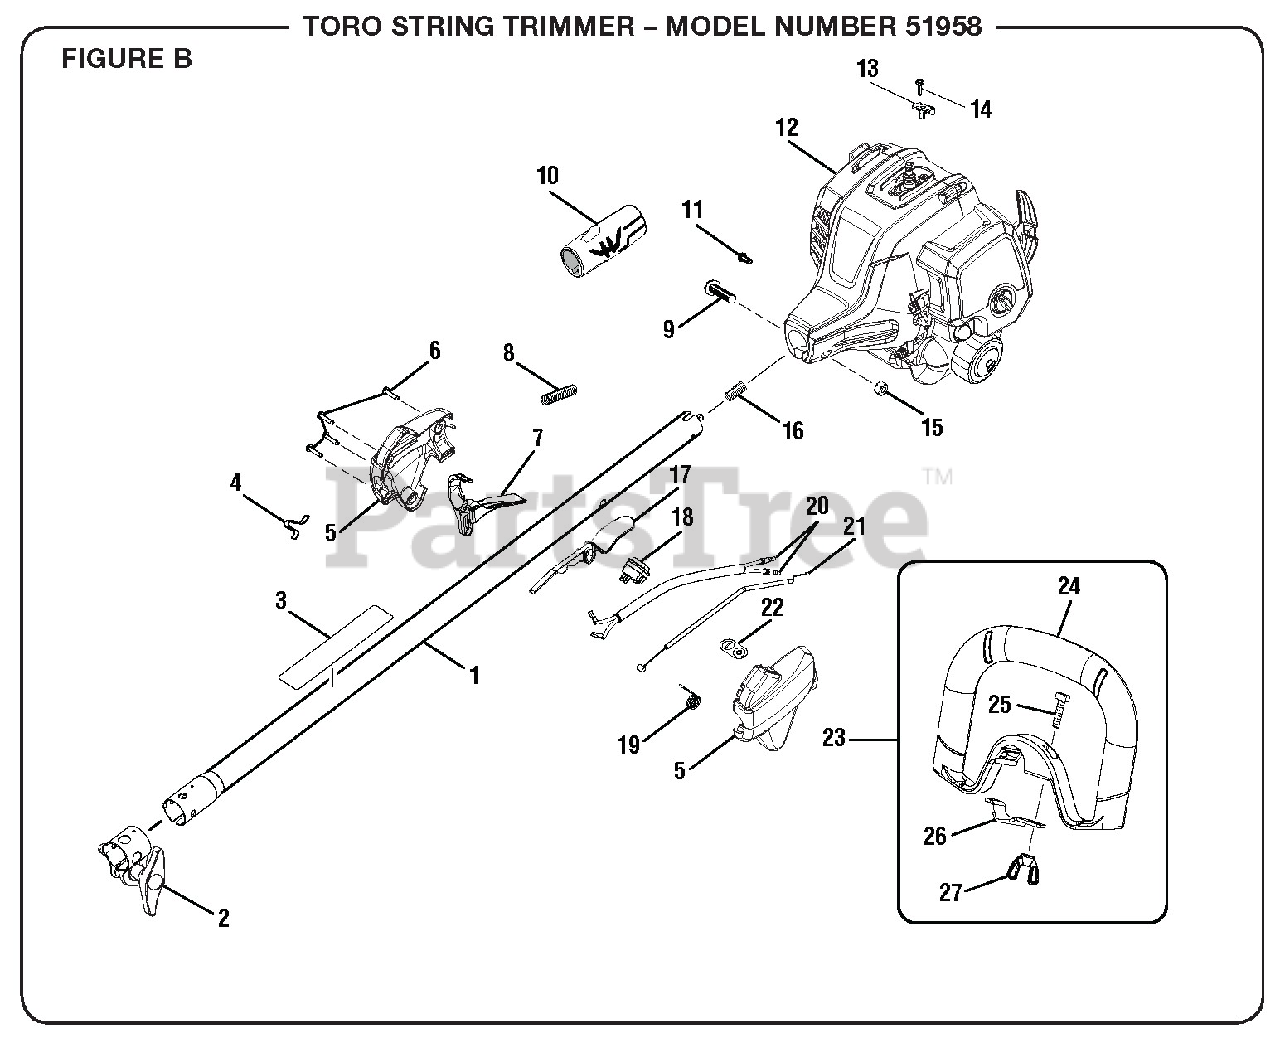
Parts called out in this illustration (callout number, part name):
1	Upper Boom Assembly
2	Boom Clamp Assembly
3	Warning Label
4	Shoulder Strap Clip
5	Control Handle Assembly
6	Screw (M4 x 20 mm, T20 Torx Hd.)
8	Corrugated Tube
9	Screw (M6 x 30 mm)
10	Rear Handle Grip
11	Screw (M4 x 8 mm, T20 Torx Hd.)
12	Powerhead Assembly
13	Throttle Cable Clamp
14	Screw (M4 x 16 mm)
15	Hex Nut (M6.3 x 1)
16	Compression Spring
17	Trigger Lock
18	On/Stop Switch
19	Throttle Cable Spring
20	Lead Assembly
21	Throttle Cable
22	On/Stop Label
23	Front Handle Assembly
24	Front Handle w/Grip
25	Screw (1/4-20 x 1 in., Sq. Hd.)
26	Front Handle Clamp
27	Wing Nut (1/4-20)
